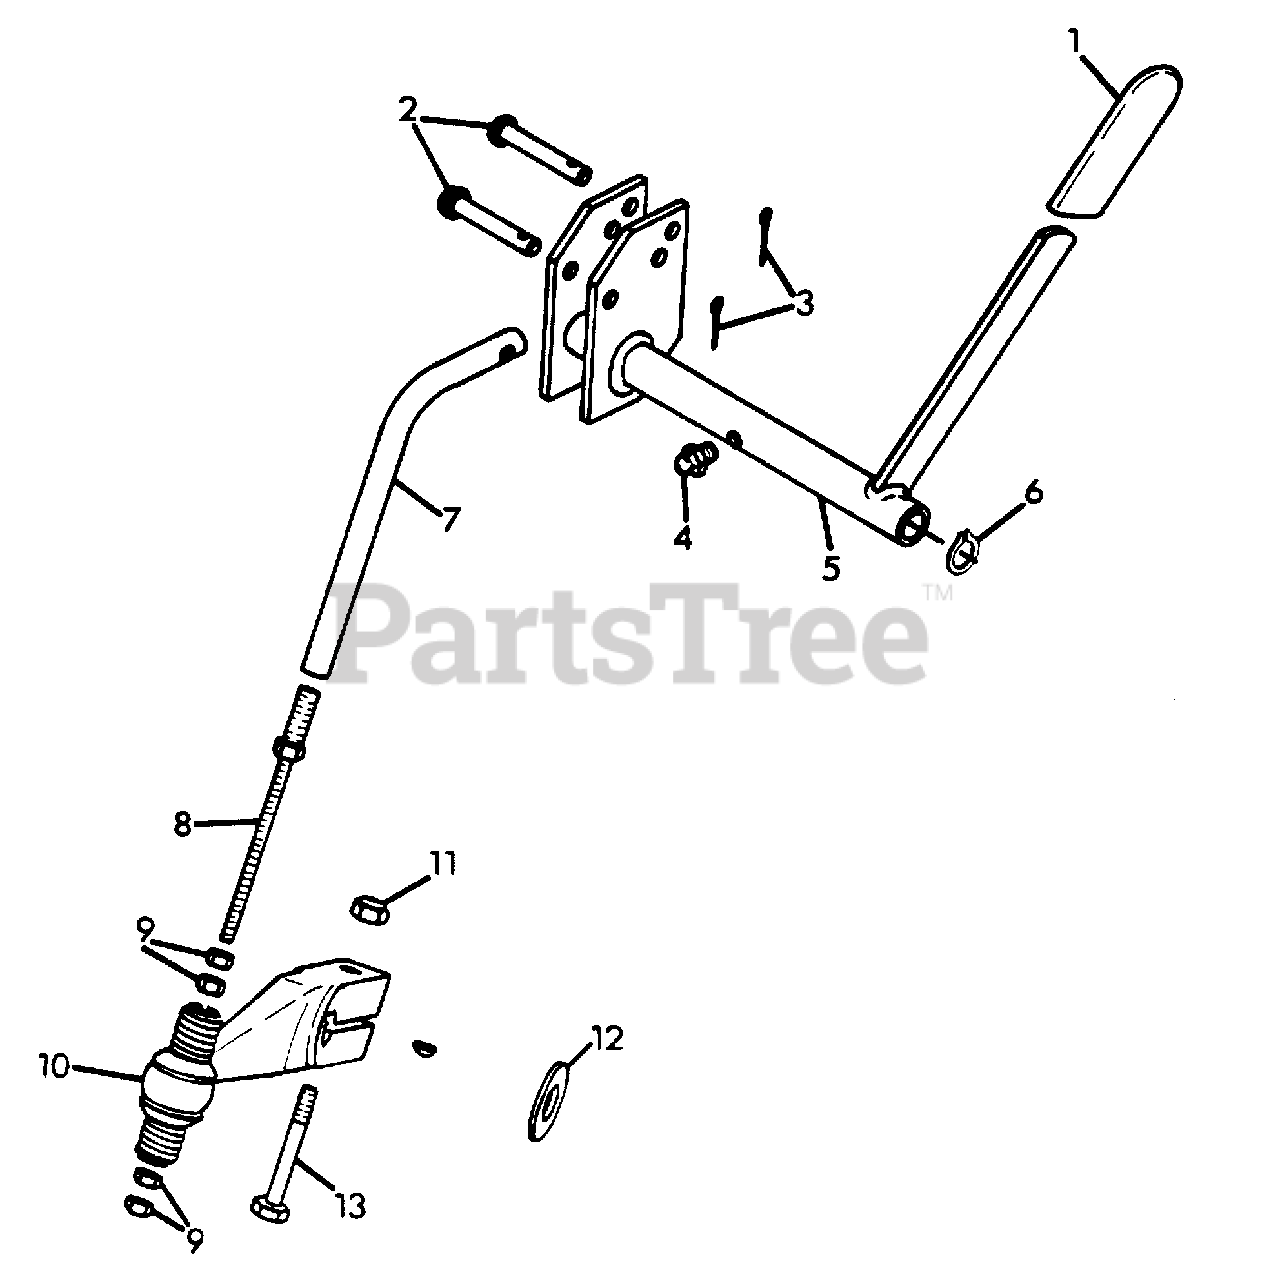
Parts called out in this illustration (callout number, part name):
1	GRIP, HANDLE
2	PIN, CLEVIS .375X1.250
3	PIN, COTTER .125X.750
4	FITTING, LUBE 1/4-28
5	LEVER, HI-LO
6	RING, RETAINING .750 SHAFT
7	ROD, HI-LO CONTROL
8	ROD, CONTROL EXTENSION
9	NUT, JAM 3/8-16
10	LEVER, HI-LO
11	NUT, LOCK 5/16-18
12	WASHER, FLAT .812X1.496X.134
13	BOLT, HEX 5/16-18X2.00
